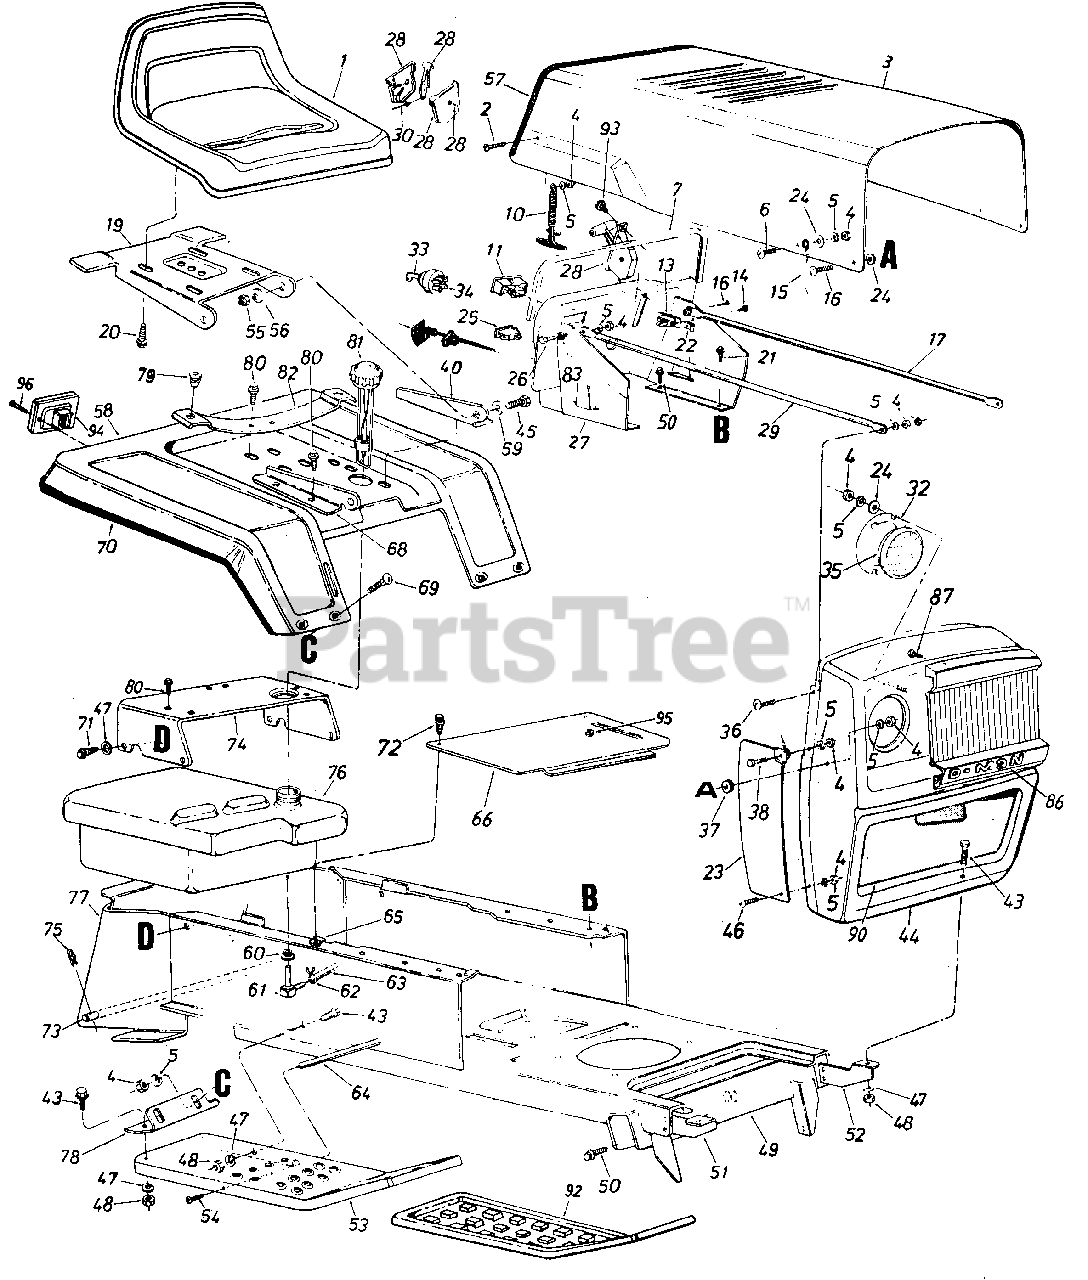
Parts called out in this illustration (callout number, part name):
1	Seat Assembly
2	Truss Mach. Scr. 1/4-20 x .50" Lg.
5	L-Wash. 1/4" Scr.
6	Truss Mach. Scr. 1/4-20 x .50" Lg.
7	Vinyl Molding Strip 29"
10	Hood Latch Ass'y.
11	Ammeter
13	Circuit Breaker 8 Amp.
14	Hex Tap Scr. #10 x .50" Lg.
15	Hood Stop
16	Truss Mach. Scr. 1/4-20 x .75" Lg.
17	Grille Positioning Rod
19	Seat Pivot Brkt.
20	Hex Wash. Hd. AB-Tap Scr. 3/8 x .75" Lg.
21	Hex Thd. Rolling Scr. 1/4" x .50" Lg.
22	Speed Nut #lOZ
23	Grille Side Panel R.H.
24	Fl-Wash. 1/4" I.D.
25	Light Switch
26	Truss Hd. Scr. 1/4-20 x 1.00" Lg.
27	Dash Panel Ass'y.
28	Throttle Control Box Comp.
29	Grille Positioning Rod
30	Throttle Control Cable
32	Head Lamp Retainer
33	Ignition Key
34	Ignition Switch
35	Head Lamp
36	Truss Machine Scr. 1/4-20 x 75 Lgs
37	Rubber Wash. .50" I.D. x 1.00 O.D. x .25 Thk.
38	Truss Mach. Scr. 1/4-20 x .5"
40	Seat Bracket L.H.
43	Hex Scr. 5/16-18 x .75" Lg.
44	Grille Ass'y.
45	Hex Bolt 5/16-18 x .75" Lg.
46	Truss Mach. Scr. 1/4-20 x .5"
47	L-Wash. 5/16" I.D.
48	Hex Nut 5/16-18 Thd.
49	Lower Frame Ass'y.
50	Hex Thd. Rolling Scr. 5/16" x.75" Lg.
51	Grille Mount Brkt. R.H.
52	Grille Mount Brkt. L.H.
53	Running Board R.H.
54	Truss Mach. Scr. 5/16-18 x .75" Lg.
55	Hex Cent. L-Nut 5/16-18 Thd.
56	Bell-Wash. .34" I.D. x .88 O.D.
57	Vinyl Moulding Strip 30"
58	Fender Ass'y.
59	Bell-Wash. .34" I.D. x .88" O.D.
60	Bushing
61	90ø Nipple
62	Hose Clamp 3/8"
63	Gas Line 46" Lg.
64	Running Board Rod
65	Speed Nut #10-24
66	Transmission Cover Ass'y.
68	Seat Bracket R.H.
69	Carr. Bolt 1/4-20 X .50" Lg.
70	Trim Strip 81" Lg.
71	Hex Thd. Rolling Scr. 5/16-24 x .75" Lg.
72	Truss Hd. Scr. #10 x .50" Lg.
73	Hitch Rod
74	Seat Mounting Channel
75	Internal Cotter Pin
76	Gas Tank
77	Hitch Plate
80	Hex Wash. Hd. Self-Tap Scr. 5/16-18 x .50" Lg.
81	Gas Gauge
82	Seat Spring
83	External Wash. 1/4" I.D.
86	Headlight Bezel
87	Self-Tap Scr. #8 x .5" Lg.
90	Grille Screen
92	Foot Pad
93	Truss Mach. AB-Tap Scr. #10 x .50" Lg.
94	Taillight
95	Snap Bushing
96	Truss AB-Tap Scr. #6 x .62" Lg.
